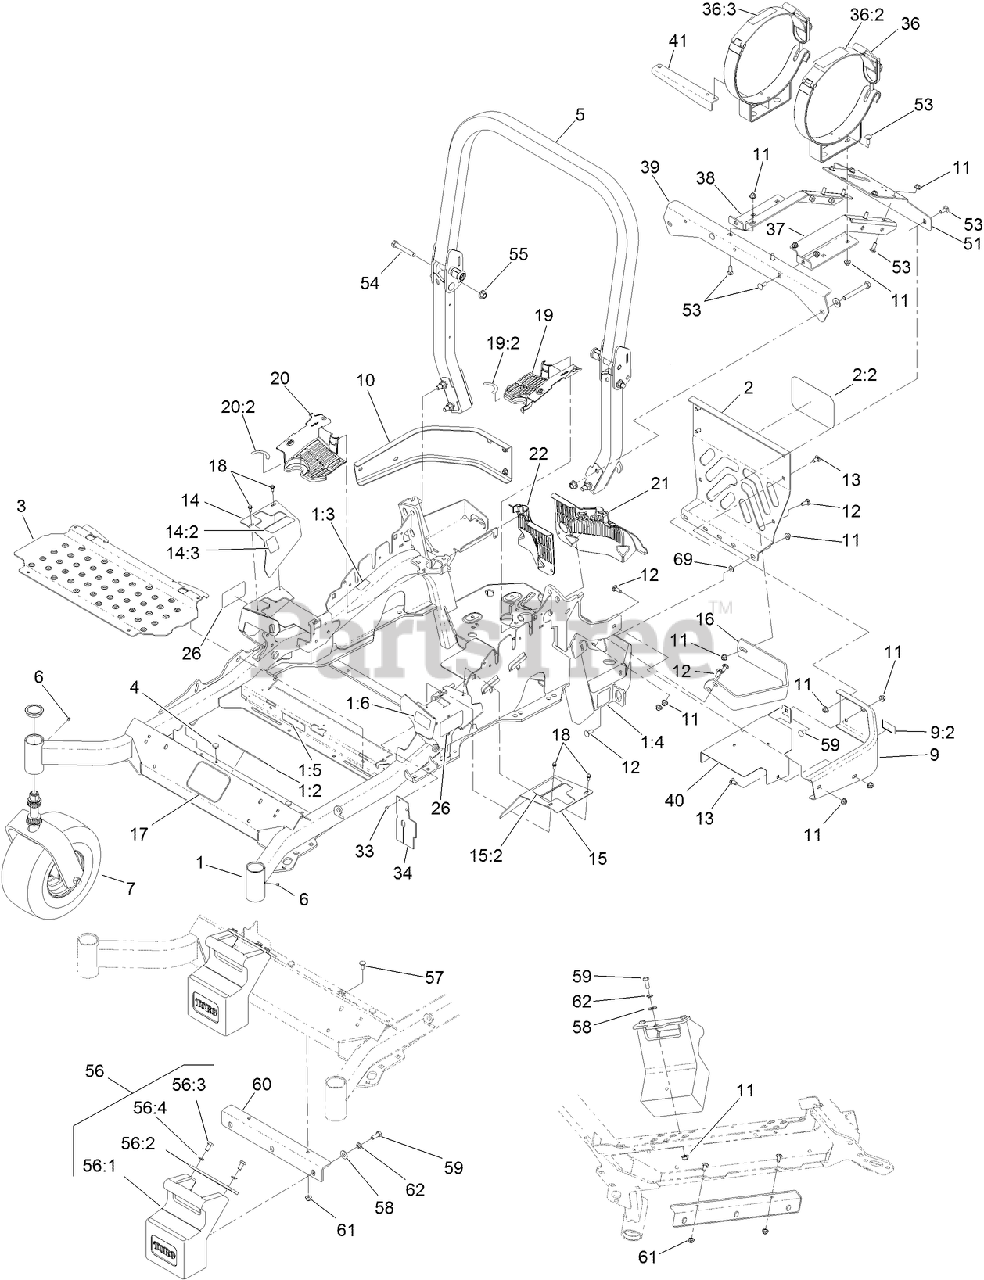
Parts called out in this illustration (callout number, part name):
1	MAINFRAME ASM
1:2	DECAL-CAUTION
1:3	DECAL-SLOPE
1:4	DECAL-BELT DRIVE
1:5	DECAL-SPARK ARRESTER
1:6	DECAL-FUEL FILL
2	REAR GUARD ASM
2:2	DECAL
3	FLOORPAN
4	BUMPER
5	ROPS ASM
7	Caster Wheel ASM
9	LH BUMPER ASM
9:2	DECAL-CAUTION
10	BUMPER-RH
11	NUT-HF, NI
12	SCREW-CARR
13	SCREW-CARR
14	RH MOTION CONTROL COVER ASM
14:2	DECAL-MOTION CONTROL
14:3	DECAL-PARK BRAKE
15	LH MOTION CONTROL COVER ASM
15:2	DECAL-MOTION CONTROL
16	GUARD-MUFFLER
17	DECAL
18	SCREW-HWH
19	LH HYDRO GUARD ASM
19:2	DECAL-HYDRO OIL
20	RH HYDRO GUARD ASM
20:2	DECAL-HYDRO OIL
21	GUARD-HYDRO, REAR (LH)
22	GUARD-HYDRO, REAR (RH)
33	RIVET-POP
34	DEFLECTOR-AIR FLOW
36	TANK BRACKET ASM (SET)
36:2	DECAL-LPG WARNING
36:3	DECAL-LPG 43.5LB TANK
37	LH LPG FRAME ASM
38	RH LPG FRAME ASM
39	SUPPORT-LPG FRAME, FRONT
40	PANEL-LPG, AC
41	PLATE-INDEX, LPG TANK
51	SUPPORT-REAR FRAME, LPG
53	BOLT-CARR
54	SCREW-HH
55	NUT-LOCK
56	WEIGHT ASM
56:1	WEIGHT-43 LB
56:2	TAB-SUPPORT, WEIGHT
56:3	SCREW-HH
56:4	WASHER-LOCK
57	SCREW-CARR
58	WASHER-FLAT
59	SCREW-HH
60	BRACKET-MOUNT, WEIGHT
61	NUT-HF, NI
62	WASHER-LOCK
69	NUT-PUSH
